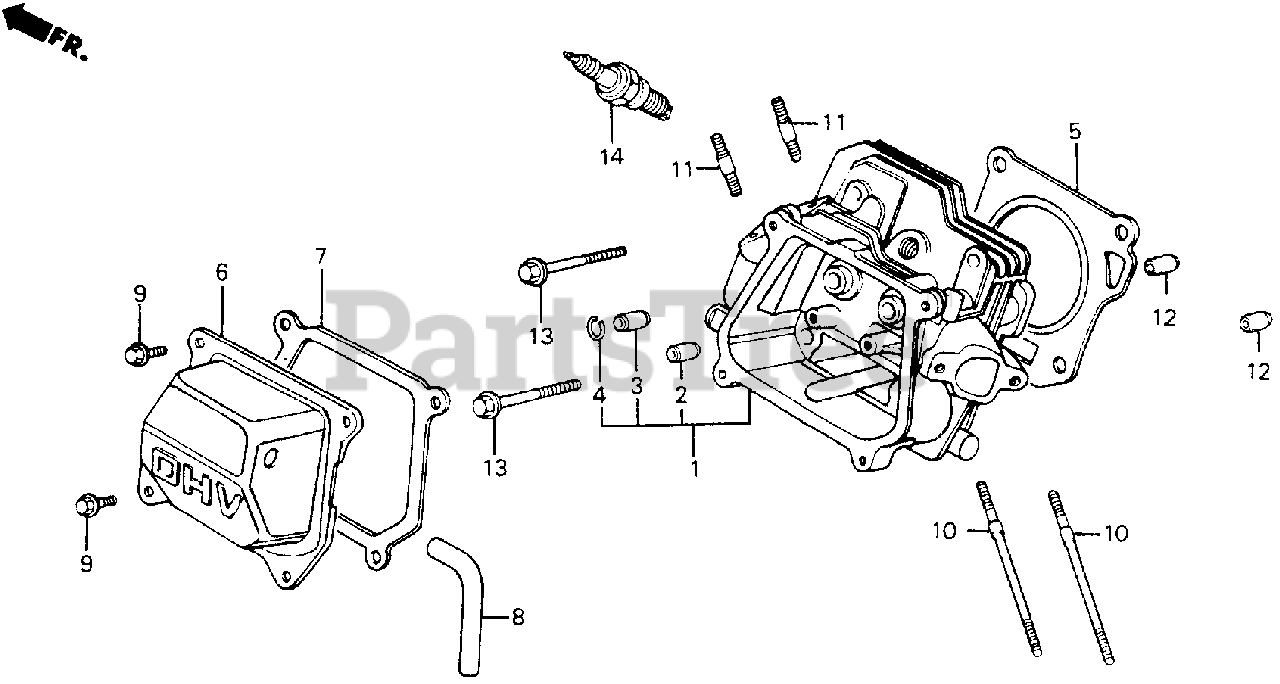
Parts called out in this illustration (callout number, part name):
1	CYLINDER HEAD
2	GUIDE, VALVE (OS)
3	GUIDE, EX. VALVE (OS)
4	CLIP, VALVE GUIDE
5	GASKET, CYLINDER HEAD
6	COVER, HEAD
7	GASKET, CYLINDER HEAD COVER
8	TUBE, BREATHER
9	BOLT, FLANGE (6X13)
10	BOLT, STUD (6X109)
11	BOLT, STUD (8X32)
12	PIN A, DOWEL (10X16)
13	BOLT, FLANGE (8X60)
14	SPARK PLUG (BPR5ES) (NGK)
14	SPARK PLUG (W16EPR-U) (DENSO)
